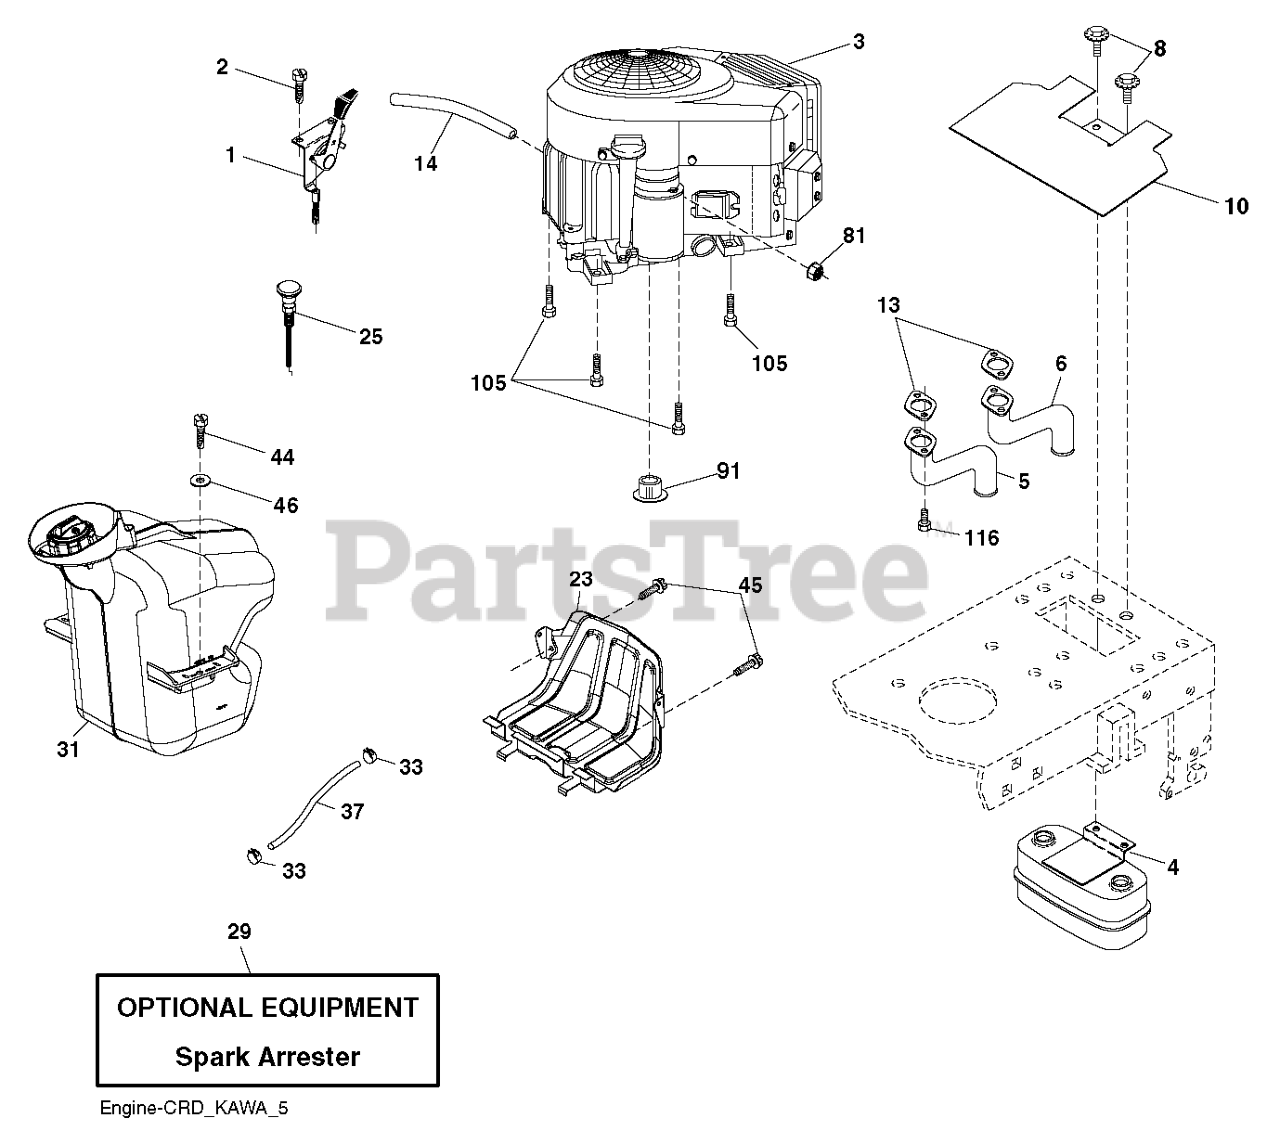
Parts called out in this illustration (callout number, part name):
1	THROTTLE CABLE
2	SCREW.#10 X 0.750.BOS
4	MUFFLER.TWIN.CYL.LOW.TONE
5	TUBE.EXHAUST.LH.FR961/FR730
6	TUBE.EXHAUST.RH.FR961/FR730
8	BOLT.5/16-18UNCX3/4 W/SEMS.BLK
10	SHIELD.HEAT.MUFFLER
14	TUBE, DRAIN OIL ASM.
23	SHIELD.BROWNING.PNT.GT.V2
25	CONTROL.CHOKE.ERGO.PUSH-IN.BLA
29	KIT.SPARK ARRESTOR 794945 B&S
31	DASH
33	HOSE CLAMP
37	LINE.FUEL.20
44	SCREW HEXWSHR 1/4-20X3/4
45	SCREW, 3/8-16X3/4
81	NUT
91	BUSHING.1.375OD
105	SCREW 3/8-16X1
116	NUT.HEX.FLANGE.TOPLOCK
